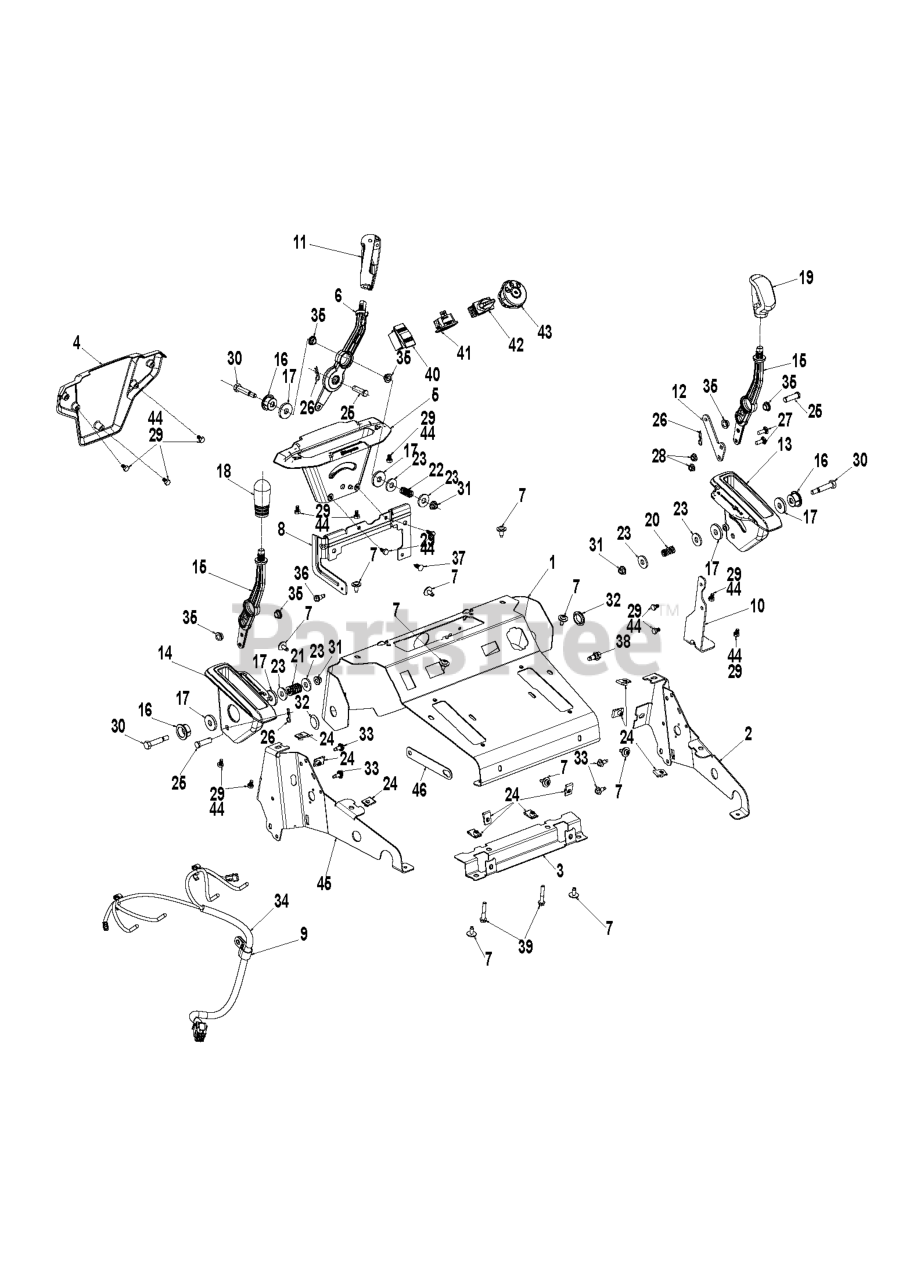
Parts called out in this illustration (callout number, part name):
6	LEVER CHUTE ROTATOR 400S CHUTE
8	BRACKET CABLE CHUTE ROTATOR
9	CLIP.CABLE.BLK
24	NUT.U-CHNL.1/4-20.550DP.350PNL
26	HAIRPIN.SOFT.ZINC.059X1.125
27	BOLT CUP HEAD SQUARE NECK BOLT
28	NUT.HEX.FLANGE.1/4
31	NUT HEXAGON FLANGE 5/16-18 ST
33	HEX.WASHER.HEAD 1/4-20 X .65
36	BOLT SHOULDER_1/4-20_TRILOB
37	FASTENER.PUSH.O.250X0.783
38	SHOULDER BOLT 5/16-18TT
39	SCREW.HEXCAP.1/4X-20X1.500
40	SWITCH HEATED GRIP BLK
41	HOUR METER SNAPIN, RECTANGULAR
42	SWITCH 3 POSITION ROTARY
43	SWITCH IGNITION 3 POSITION 6-W
